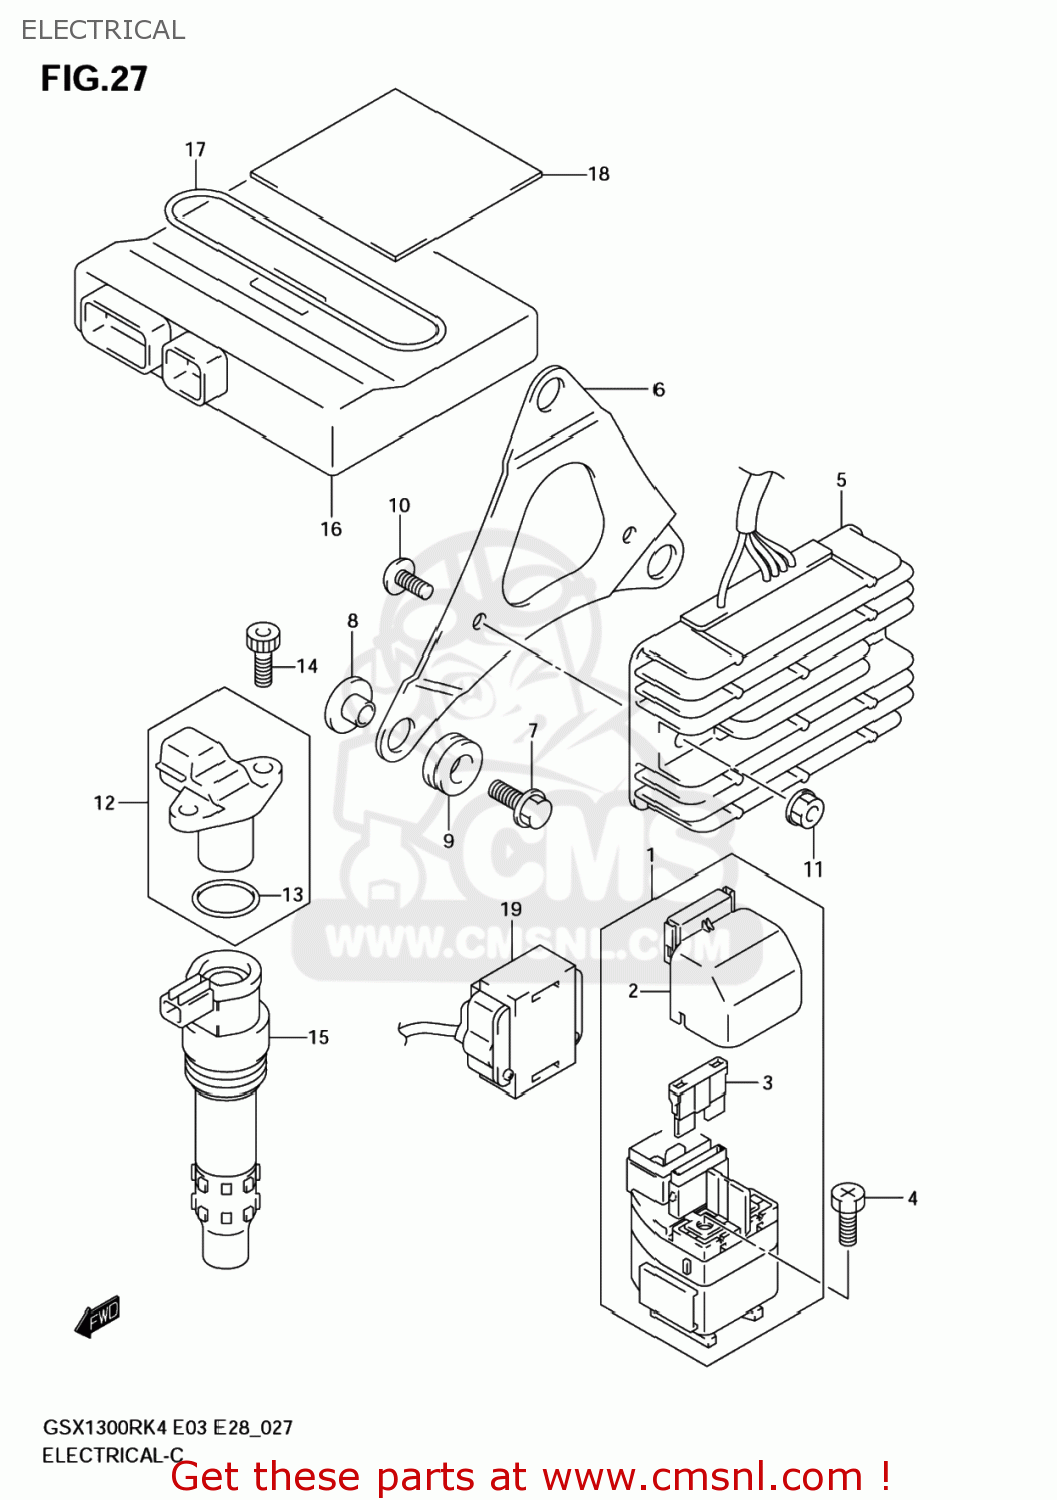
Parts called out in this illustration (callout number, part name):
1	RELAY ASSY,STARTING MOTOR
2	COVER,STARTER RELAY
3	FUSE(30A)
4	SCREW(6X8)
5	RECTIFIER ASY
6	BRACKET,RECTIFIER
7	BOLT(6X25)
8	WASHER
9	CUSHION
10	SCREW
11	NUT
12	SENSOR ASSY,CAM POSITION
13	PACKING (NAS)
14	BOLT
15	COIL ASSY,IGNITION
16	CONTROL UNIT,FI
17	BAND,BATTERY
18	PROTECTOR(40X40X16)
19	SENSOR ASSY,FUEL CUT
